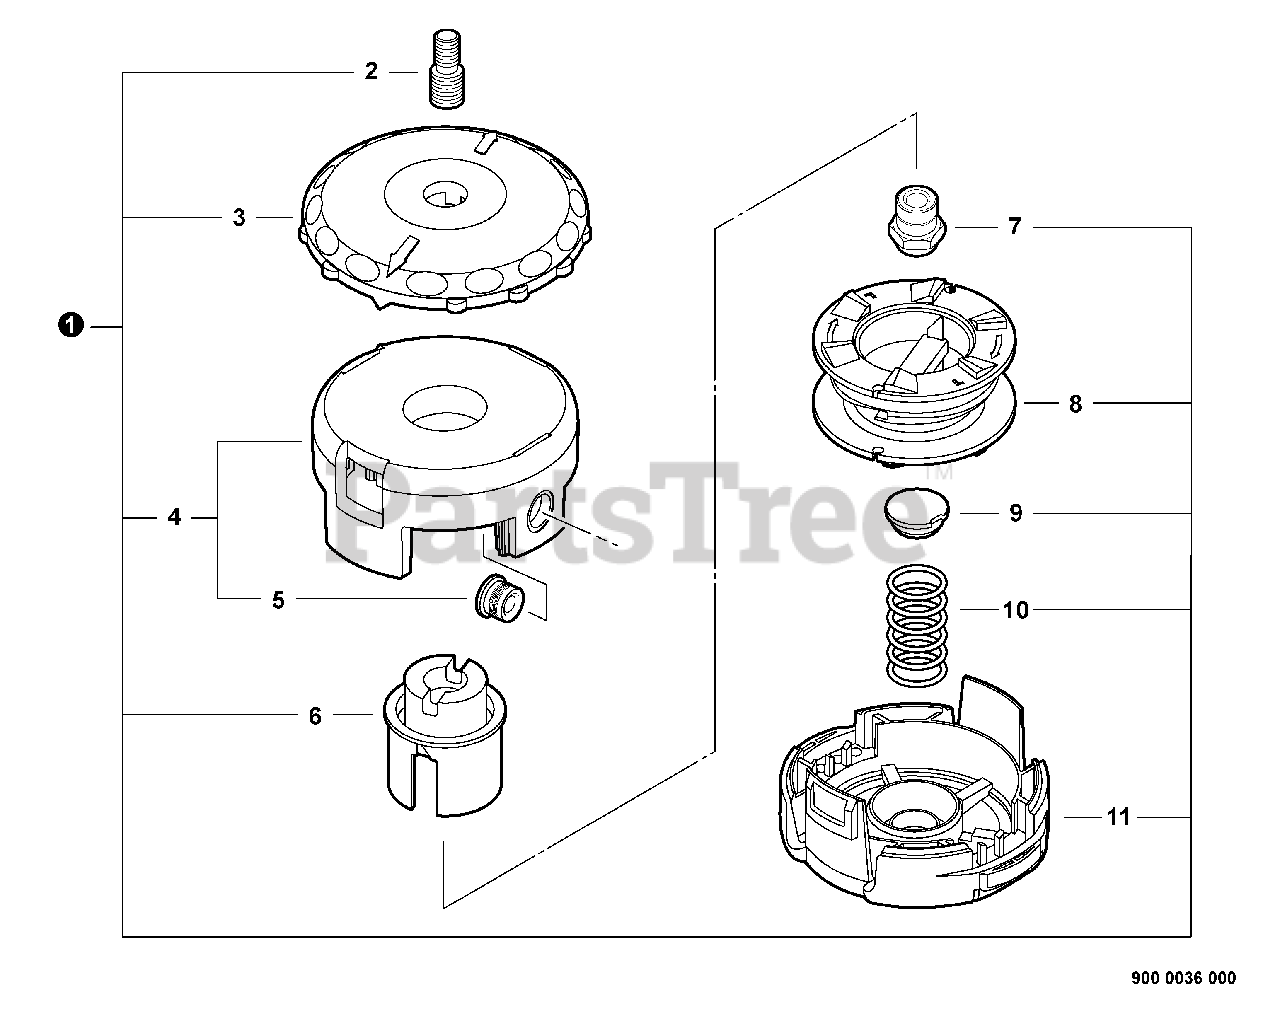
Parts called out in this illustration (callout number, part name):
1	TRIMMER HEAD, SPEED-FEED® 400
2	BOLT, STUD M8×1.25 RH/3/8"-24UNF-2A BLACK
4	HOUSING ASSY, SPOOL
6	HUB (RH) WHITE
7	BUSHING 3/8"-24 RH BLACK
9	CAP, SPRING
10	SPRING, GOLD
11	COVER, SPOOL
